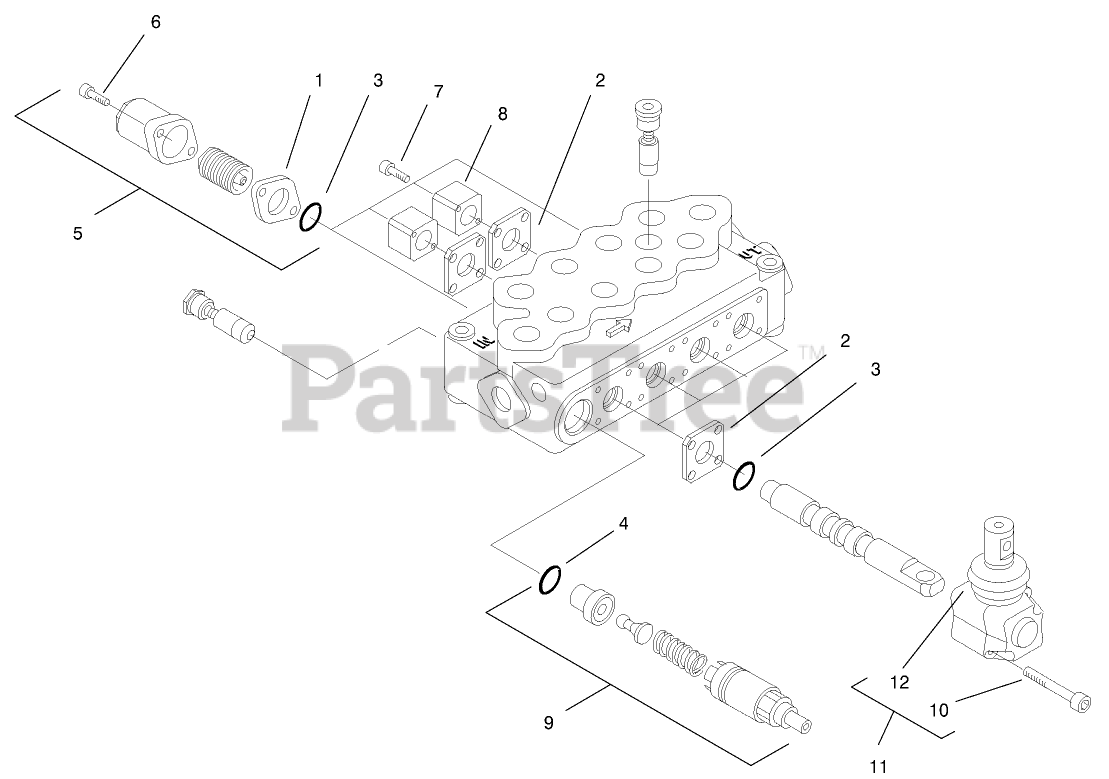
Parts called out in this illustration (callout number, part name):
1	GASKET
2	GASKET
5	STANDARD SPRING KIT
5	HIGH FORCE SPRING KIT
6	SCREW-CAP, END
8	BLOCK-MOUNT, SWITCH
9	VALVE-RELIEF
11	OPERATOR ASM
